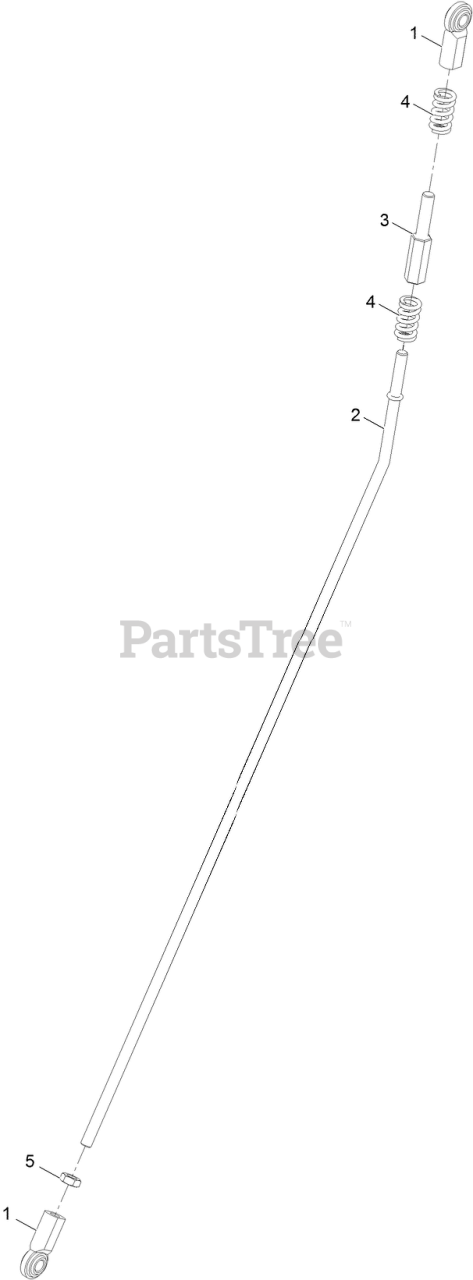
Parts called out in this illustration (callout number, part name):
1	JOINT-BALL, END
2	LINKAGE-MOTION
3	ROD-ADJUSTMENT
4	SPRING, COMPRESSION
5	NUT-HJ
